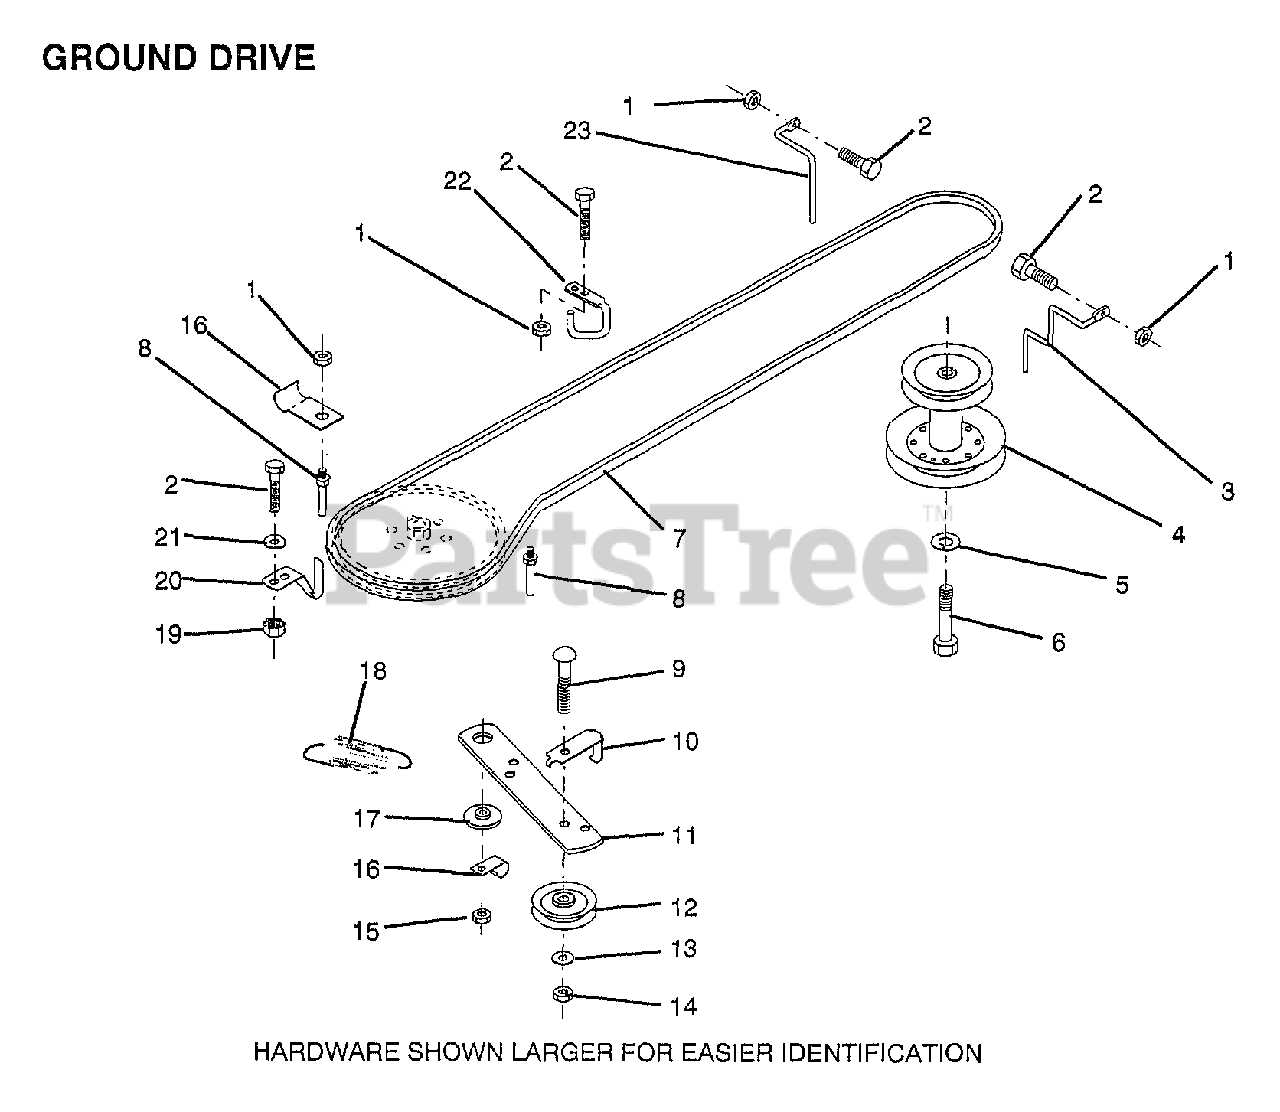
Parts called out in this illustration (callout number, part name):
2	BOLT
3	KEEPER ENG BEL LH
5	LOCKWASHER
6	BOLT
7	BELT
8	"KEEPER,DRIVE BELT"
9	BOLT
10	"KEEP,IDLER DR BEL"
13	WASHER
14	LOCKNUT
16	"CLIP,INSULATOR"
17	SPACER RETAINER
20	"KEEPER,DR BELT "
21	WASHER
22	"KEEPER,FRA DR BEL"
23	KEEPER ENG DR RH
